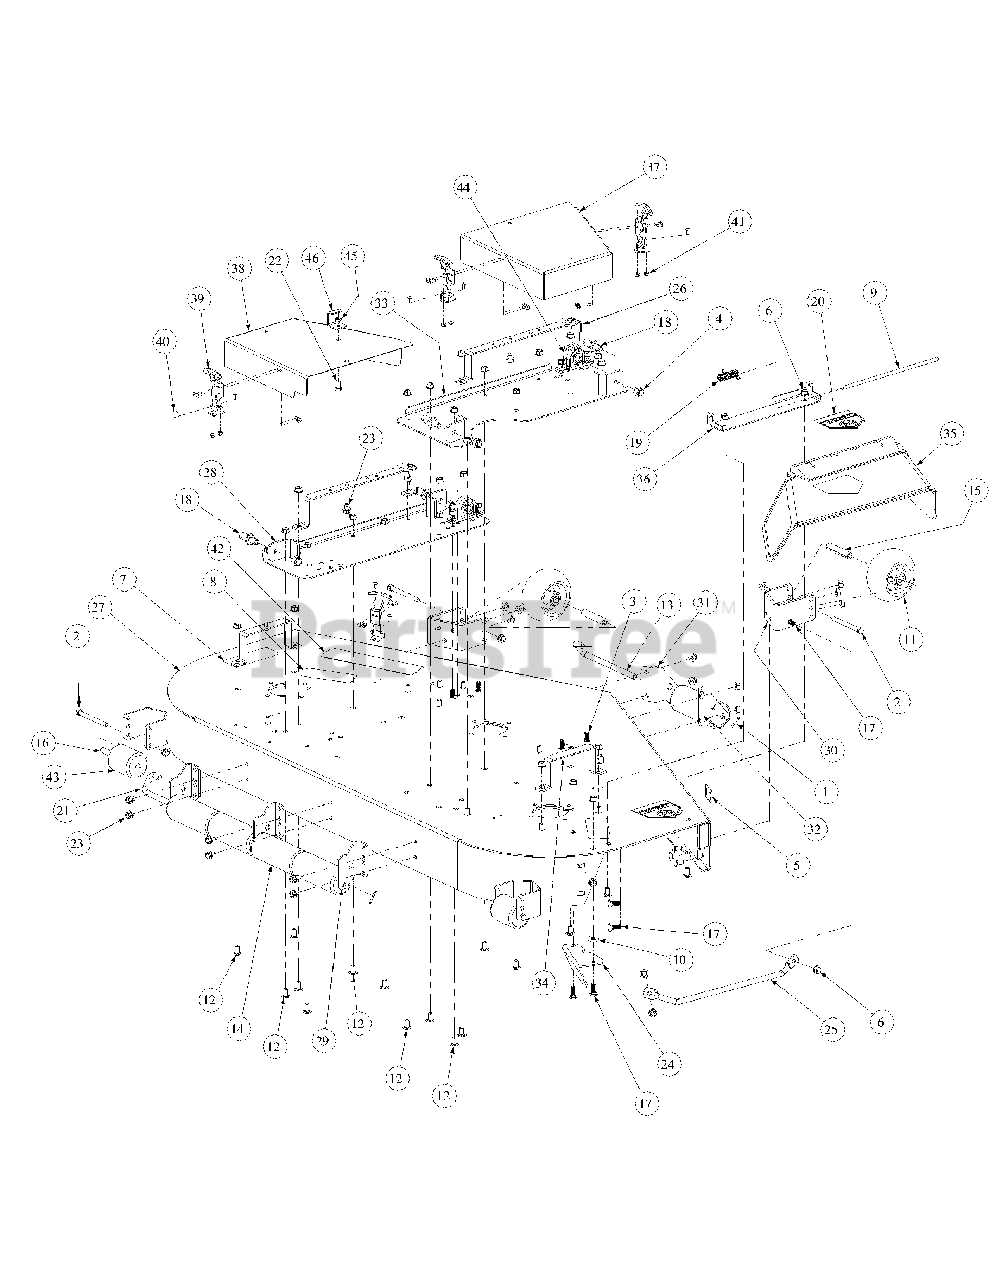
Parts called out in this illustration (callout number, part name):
1	Cotter Pin, .125 Dia. x 1.0
2	Hex Cap Screw, 3/8-16, 3.75
3	Carriage Screw, 3/8-16 x 1.25
4	Lock Nut, Nylon Insert, 1/2-13
5	Label, 60"
6	Flange Lock Hex Nut, 3/8-16
7	Decal, Rotating Blade
8	Decal, Warning Shield Missing
9	Chute Deflector Rod
10	Idler Washer
11	Complete Wheel, 5.00 Dia.
12	Carriage Bolt, 3/8-16 x .75 Lg.
13	Roller Pin, 1/2 Dia. x 7.31 Lg.
14	Front Roller
15	Wheel Spacer
16	Spacer, .385 x .50 x 3.045
17	Carriage Bolt, 3/8-16 x 1
18	Pin, 5/8 Dia. x 1.2 Lg.
19	Torsion Spring, 0.4ID x 2.16Lg
20	Decal, Danger Hand and Feet
21	Roller Pin
22	Hex Cap Screw, 5/16-18 x .75
23	Hex Index Washer Screw, 3/8-16, .5
24	Chute Bracket
25	Finger Guard
26	Belt Cover Support
27	60 Deck Assembly
28	Left Hand Mount Deck Bracket Assembly
29	Deck Roller Mount Bracket
30	Anti-Scalp Wheel Front Mount Bracket
33	Right Hand Deck Bracket Assembly
34	Outer Belt Cover Support Assembly
35	Chute Deflector
36	Chute Deflector Bracket
37	Right Hand Deck Belt Cover
38	Left Hand Deck Belt Cover
39	T-Handle Latch Draw
40	Phillips Head Screw, 10-32
41	Lock Nut, Nylon Insert, 10-32
42	Commercial Mower Label
43	Grass Catcher Roller
44	Pillow Block
45	Nut, 5/16-18, Hex Flange Lock
46	Stop Bracket
